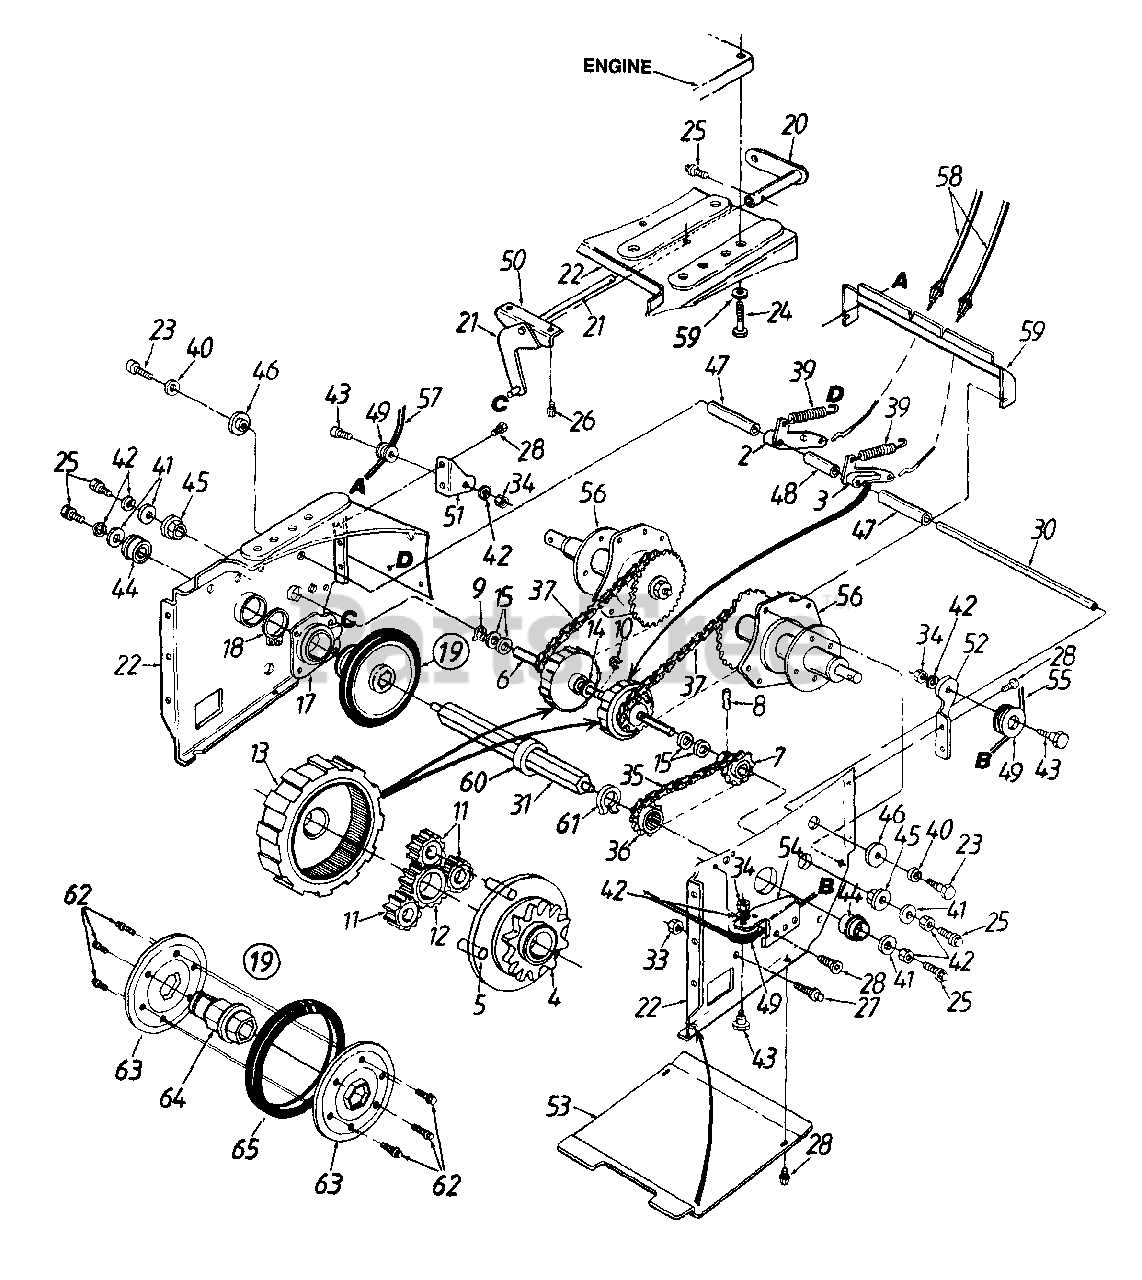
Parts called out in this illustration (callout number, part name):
2	R.H. Dog Ass'y.
3	L.H. Dog Ass'y.
4	Carrier
5	5/16" Dowel Pin
7	12 Tooth Sprocket
8	Spring Pin 3/16" Dia. x 1" Lg.
9	Snap Ring .56" Dia.
10	Snap Ring .625" Shaft
11	12 Tooth Gear
12	18 Tooth Gear
13	Ring Gear
14	Fl-Wash. 5/8" I.D. x 1" O.D.
15	Fl-Wash. .57" I.D. x 1.12" O.D.
17	Friction Wheel Brg. Ass'y.
18	Retaining Ring 1.375" Dia. Shaft
19	Friction Wheel
21	Shift Rod Ass'y.
23	Hex Bolt 5/16-18 x .75" Lg.
24	Hex L-Wash. TT-Tap Scr. 3/8-16 x 1.25" Lg.
25	Hex TT-Tap Scr. 1/4-20 x .75" Lg.
26	Hex Wash. Hd. Tap Scr. 1/4-20 x .38" Lg.
27	Hex Wash. TT-Tap Scr. 1/4-20 x 1" Lg.
28	Torx Mach. AB-Tap Scr. 1/4 x .62" Lg.
30	Actuator Shaft
33	Hex Nut 1/4-20 Thd.
34	Hex Jam Nut 1/4-20 Thd.
35	#420 Chain - 1/2 Pitch x 30 Link (Endless)
36	11 Tooth Sprocket
37	#420 Chain - 32 Links (Endless)
39	Extension Spring 2.03" Lg.
40	L-Wash. 5/16" I.D.
41	Fl-Wash. 1/4" I.D. x .93" O.D.
42	L-Wash. 1/4" I.D.
43	Shld. Bolt 5/16" Dia. x .35" Lg.
44	Ball Brg. w/Snap Ring
45	Hex Flange Bearing
46	Shld. Spacer .5" Dia. x .27" Lg.
47	Split Shld. Spacer 2.69" Lg.
48	Split Shld. Spacer 1.77" Lg.
49	Cable Roller
56	Track Hub Ass'y.
57	Drive Clutch Cable
58	Track Steer Cable w/Trigger
59	Fl-Wash. .406" I.D. x 1" O.D.
60	Spacer 1.02" I.D. x 1.25" O.D.
62	Hex Wash. Hd. TT-Tap Scr. 1/4-20 x .5" Lg.
63	Friction Plate
64	Friction Wheel Hub
65	Friction Wheel Rubber
